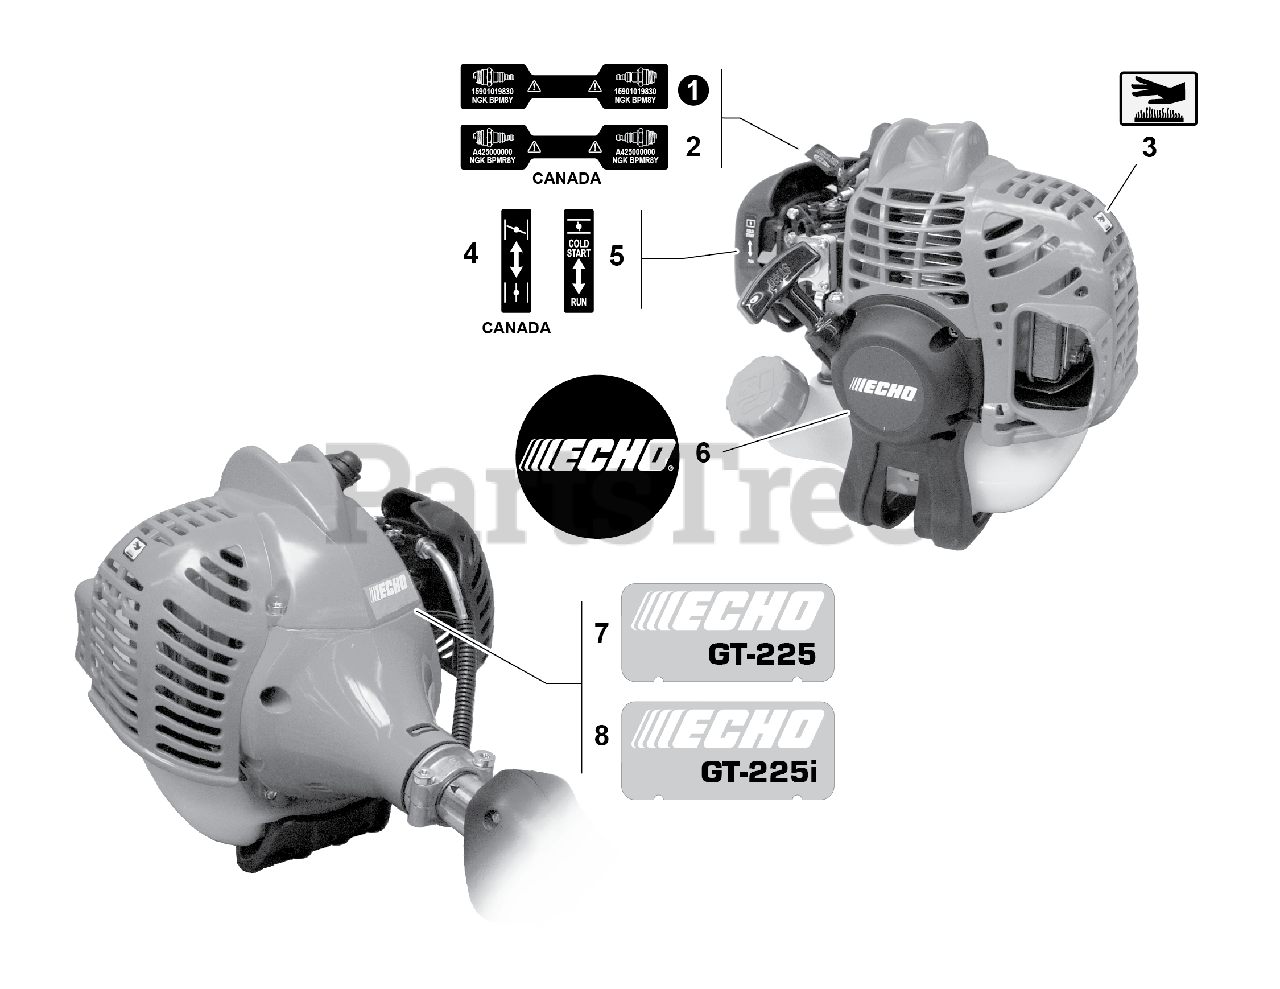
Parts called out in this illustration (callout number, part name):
1	LABEL - SPARK PLUG -- BPM8Y
2	LABEL - SPARK PLUG -- BPMR8Y
3	LABEL - HOT SURFACE
4	LABEL - CHOKE
5	LABEL - CHOKE
6	LABEL - ECHO
7	LABEL - MODEL -- GT-225
8	LABEL - MODEL -- GT-225i
